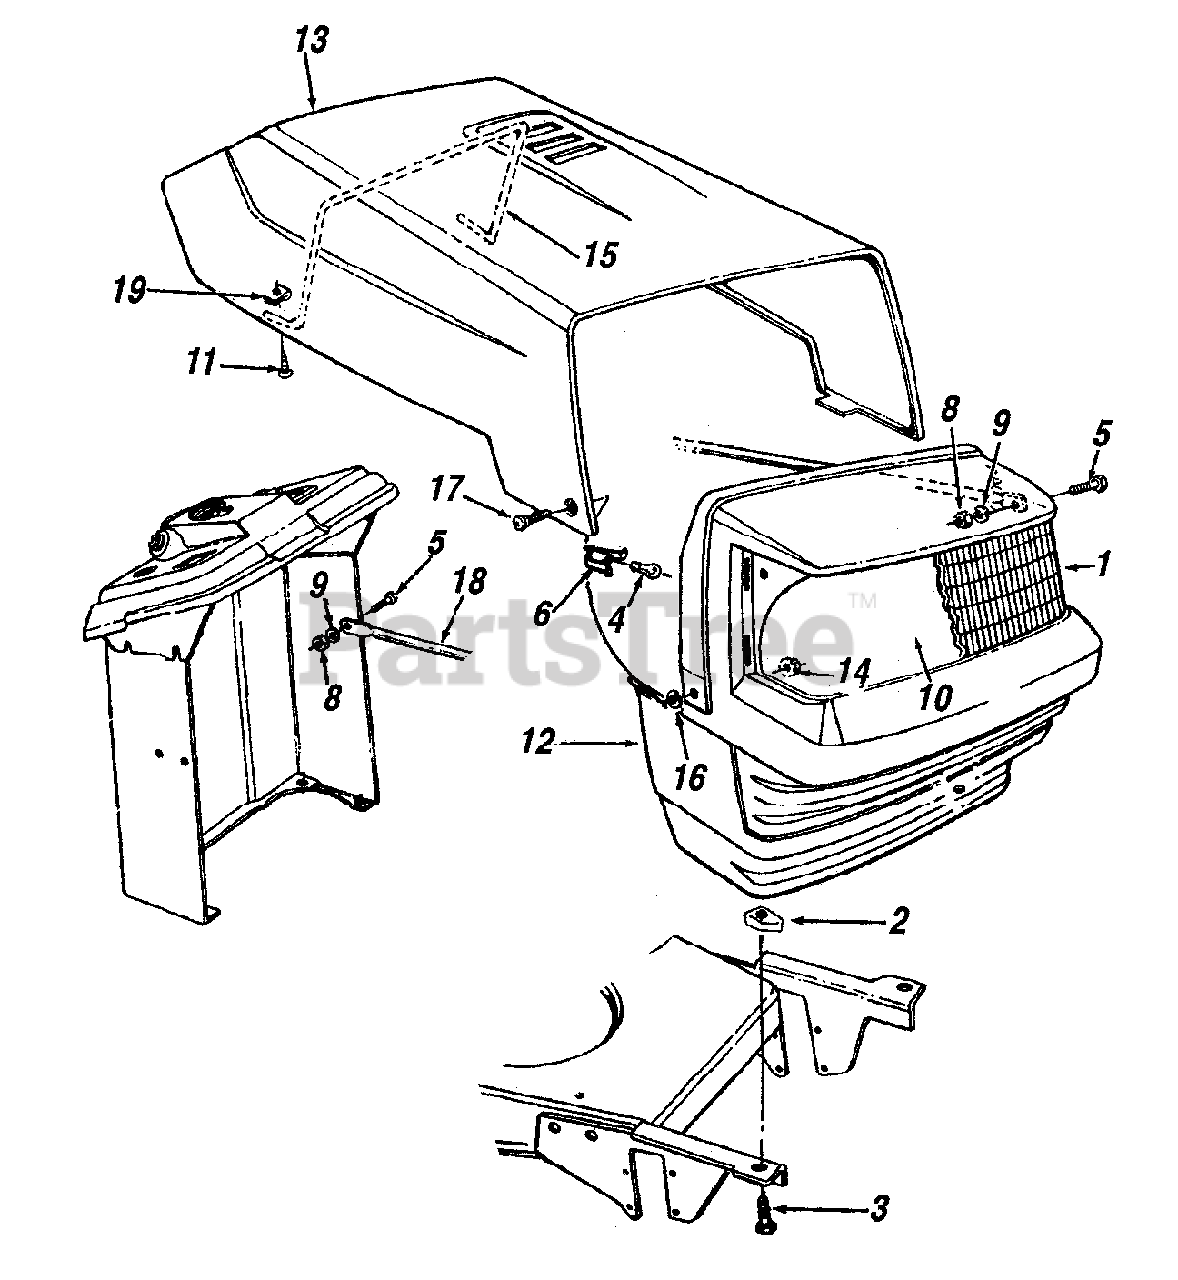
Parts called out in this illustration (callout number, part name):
1	Lens
2	U-Nut 5/16-18 Thd.
3	Hex Bolt 5/16-18 x .75" Lg.
5	Hex Bolt 1/4-20 x .62" Lg.
6	Socket
8	Hex Nut 1/4-20 Thd. Gr.5
9	Lock Washer 1/4" I.D.
10	Grille Reflector Label
11	Hex Tap Screw #10-16 x .75" Lg.
12	Grille
15	Hood Spring
16	Flat Washer .28" I.D. x .75" O.D.
17	Shoulder Bolt
